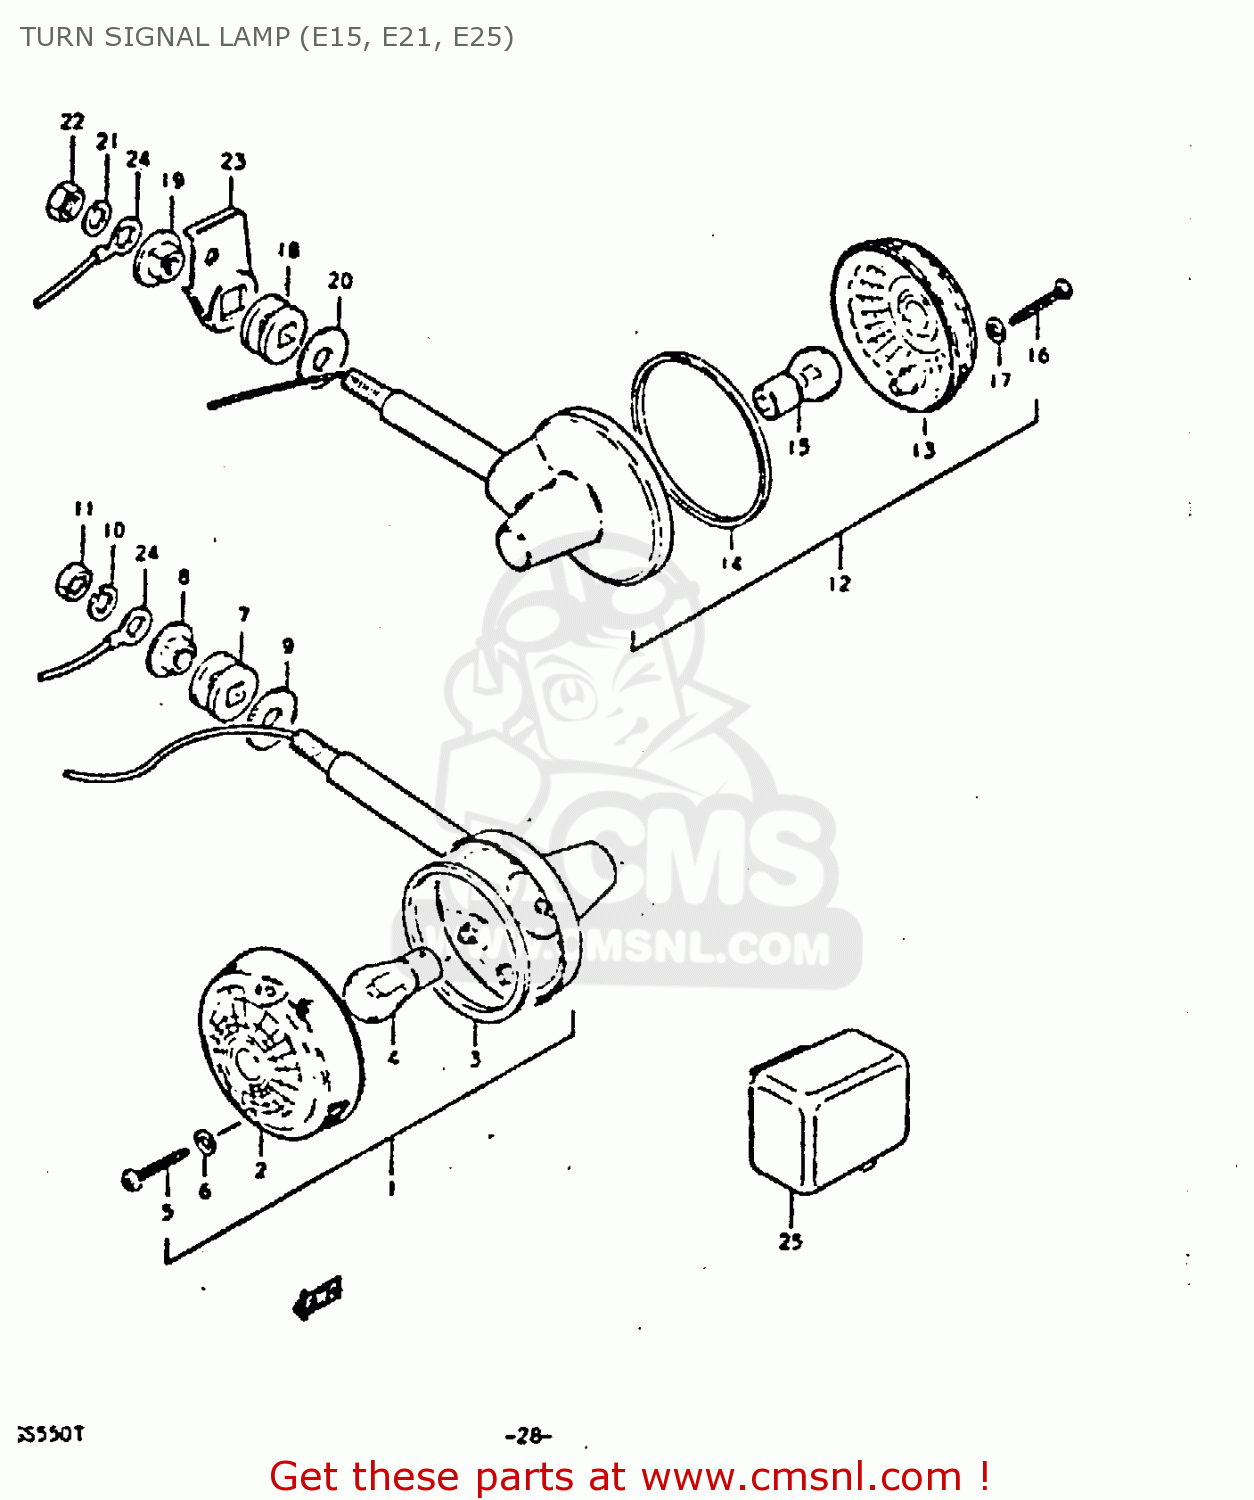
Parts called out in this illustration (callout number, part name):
1	LAMP ASSY, FRONT TURN SIGNAL
2	LENS
3	GASKET (NAS)
4	BULB 12V 21W
5	SCREW
6	GASKET (NAS)
7	CUSHION
8	SPACER,RR TURNSIGNAL LAMP
9	WASHER
10	LOCK WASHER
11	NUT
12	LAMP ASSY, REAR TURN SIGNAL
13	LENS
14	GASKET (NAS)
15	BULB 12V 21W
16	SCREW
17	GASKET (NAS)
18	CUSHION
19	SPACER,RR TURNSIGNAL LAMP
20	WASHER
21	LOCK WASHER
22	NUT
23	BRACKET,RR TURNSIGNAL LAMP,R
24	WIRE
25	RELAY,TURN SIGNAL
